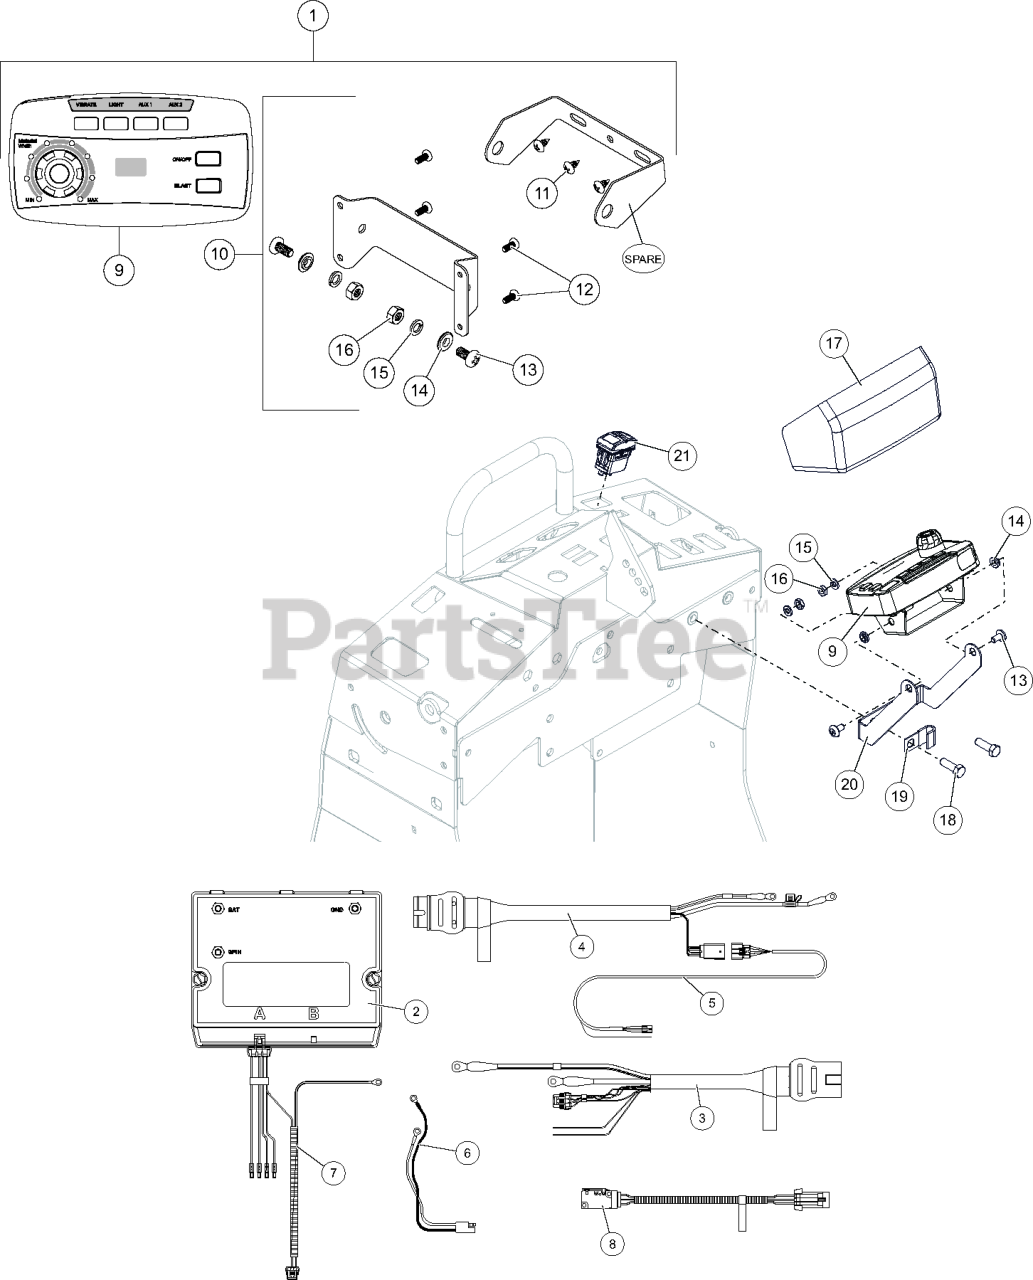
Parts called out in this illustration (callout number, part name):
1	SPREADER CONTROL KIT
2	SPREADER MODULE, 3-POST
3	SPREADER HARNESS, 7-PIN
4	HARNESS, ACCESSORY (VEHICLE)
5	HARNESS, CONTROLLER - SALT
6	SPINNER MOTOR HARNESS REV PIN-OUT
7	CONNECTOR W/5 WIRES, 10 PIN
8	SWITCH ASSEMBLY
9	SPREADER CONTROL KIT
10	CONTROL BRACKET KIT
11	#10 X 3/8 PAN HEAD TAPPING SCREWS SS
12	#8 X 3/8 PAN HEAD MACHINE SCREW
13	SCR, MCH .25-20 X .500 TXTR ZB500
14	BUSHING, PIVOT
15	WSHR,LK-REG .250X.062 ZCC
16	NUT-JAM .250-20 G2 ZCC
17	COVER, CONTROL
18	BLT,HEX .31-18X1.00 G5 ZCC
19	J-CLAMP
20	BRACKET, CONTROL MOUNT
21	SWITCH- ROCKER - ON-OFF-NO
